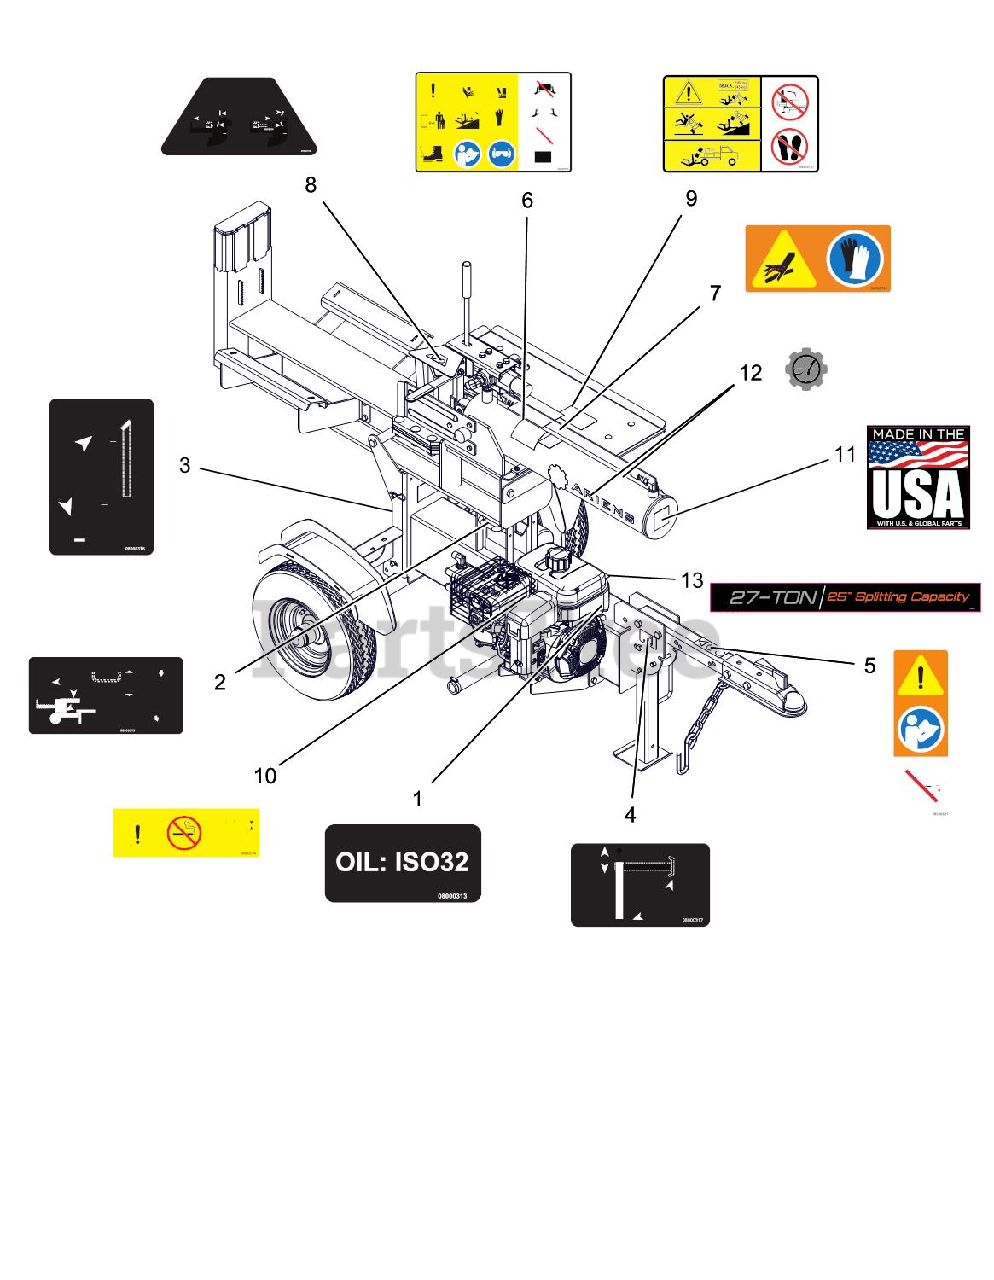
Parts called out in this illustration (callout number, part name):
1	DECAL, LOG SPLITTER-HYD OIL
2	DECAL, LOG SPLITTER-TILT OP
3	DECAL, LOG SPLITTER-REAR STAND
4	DECAL,LOG SPLITTER-FRONT STAND
5	DECAL, NO TOWING
6	DECAL,DANGER LOG SPLITTER
7	DECAL,HYD WARNING
8	DECAL,RAM OPERATION
9	DECAL,SPLITTER TABLE
10	DECAL,FUEL WARNING
11	DECAL, MADE IN USA
12	DECAL-ARIENS-CYLINDER
13	DECAL-CRADLE-27 TON
